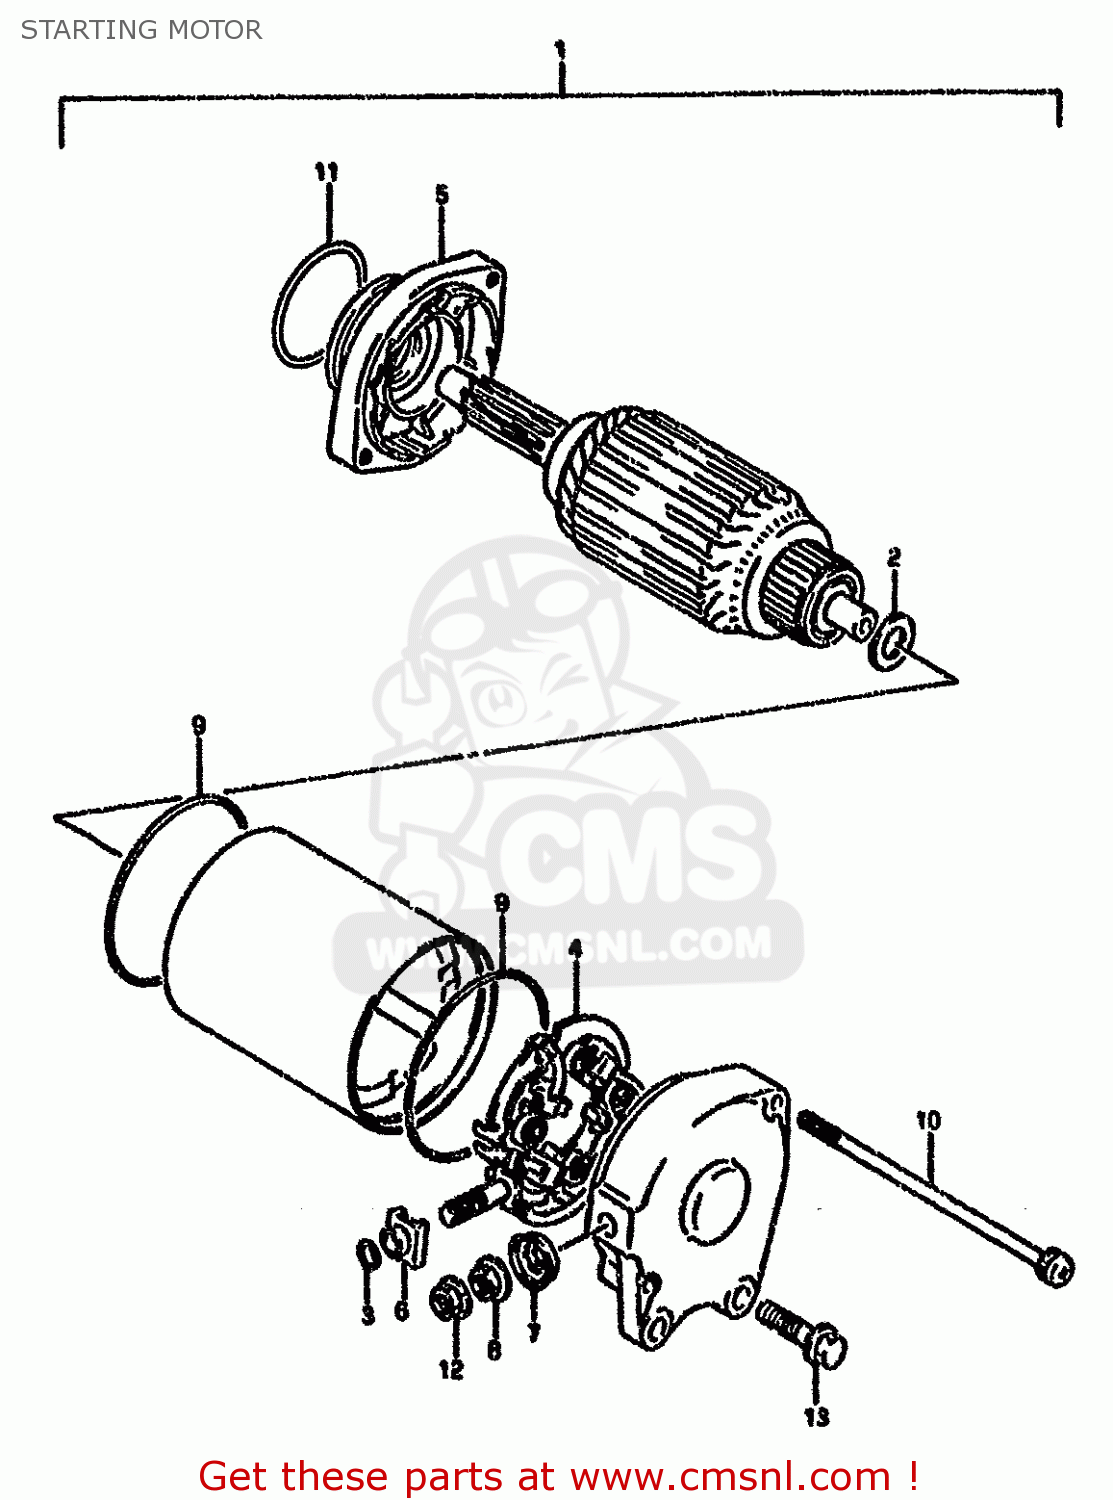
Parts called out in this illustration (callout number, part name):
1	MOTOR ASSEMBLY,STARTING
2	SHIM SET,STARTING MOTOR
3	O RING
4	HOLDER SET,BRUSH
5	BRACKET SET
6	BUSHING
7	BUSHING
8	NUT
9	O RING
10	BOLT
11	O-RING (D:2.0)
12	NUT
13	BOLT
